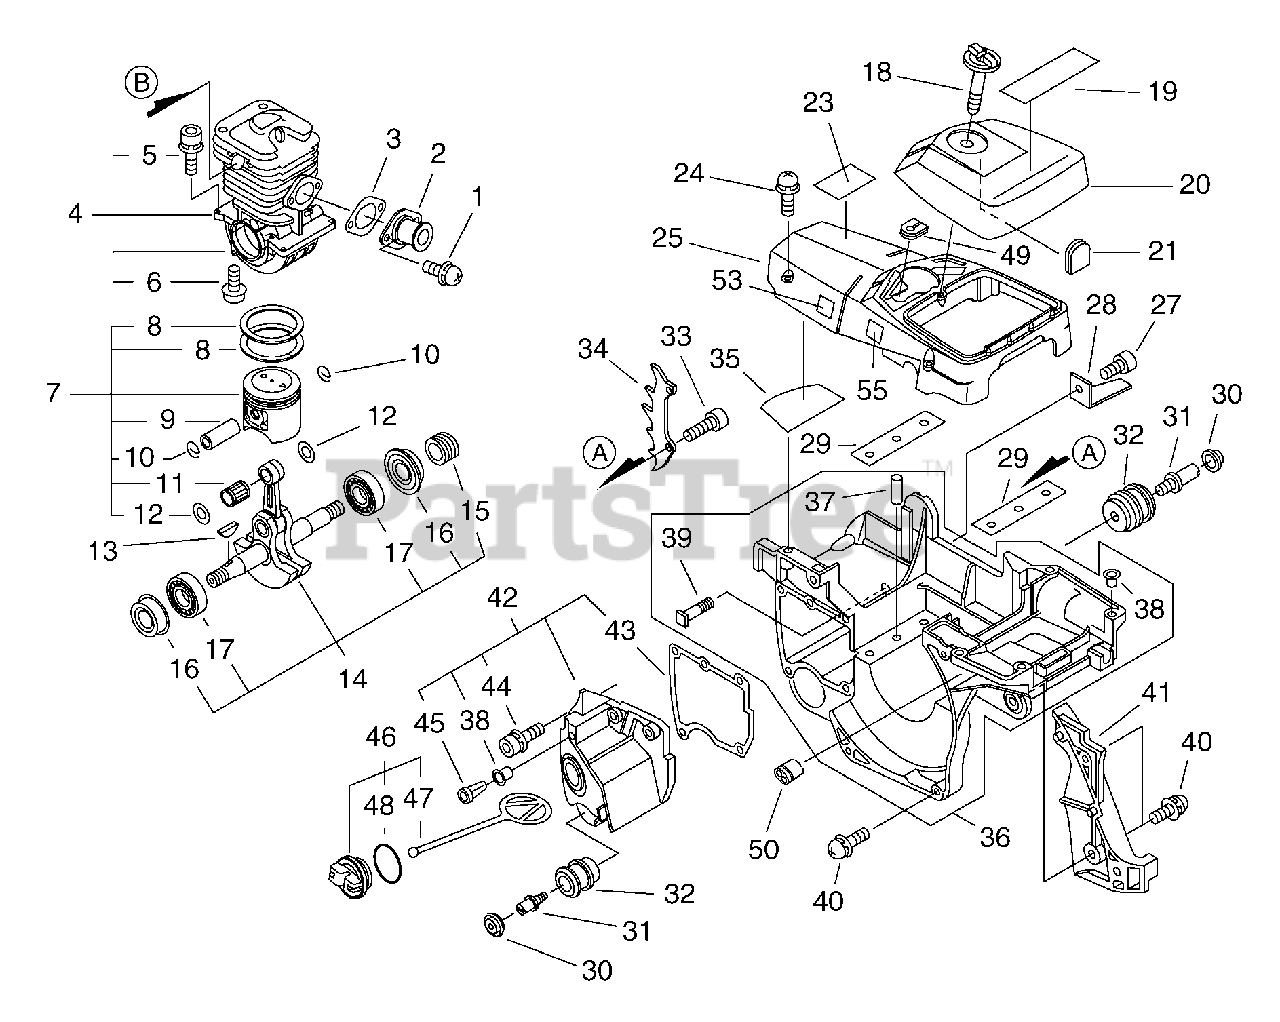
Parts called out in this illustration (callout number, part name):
1	SCREW - 5X12
2	ADAPTOR, INTAKE
3	GASKET, INTAKE
4	CRANKCASE SET
5	SCREW - 5X22
6	SCREW - 5X20
7	PISTON KIT
8	RING, PISTON
9	PIN, PISTON
10	RING, RETAINING
11	BEARING, NEEDLE
12	WASHER - 11
14	CRANKSHAFT ASSY
15	GEAR - WORM
16	SEAL, OIL
17	BEARING, BALL - 6202
18	THUMBSCREW
19	LABEL - MODEL CS-510
20	COVER, AIR FILTER
23	LABEL - CAUTION
24	SCREW - 5
25	COVER, ENGINE
27	SCREW - 5X14
28	CATCHER, CHAIN
30	CAP, CUSHION
33	SCREW - 5X12
35	DEFLECTOR, HEAT
36	ENGINE COVER ASSY
37	PIN - LOCATING
39	STUD, GUIDE BAR
40	SCREW - 5X16
41	GUARD, SPROCKET
42	OIL TANK ASSY
43	GASKET, OIL TANK
44	SCREW - 4X16
45	VENT, TANK
46	CAP ASSY - BLACK
47	CONNECTOR, CAP
48	O-RING - 25
49	GROMMET
